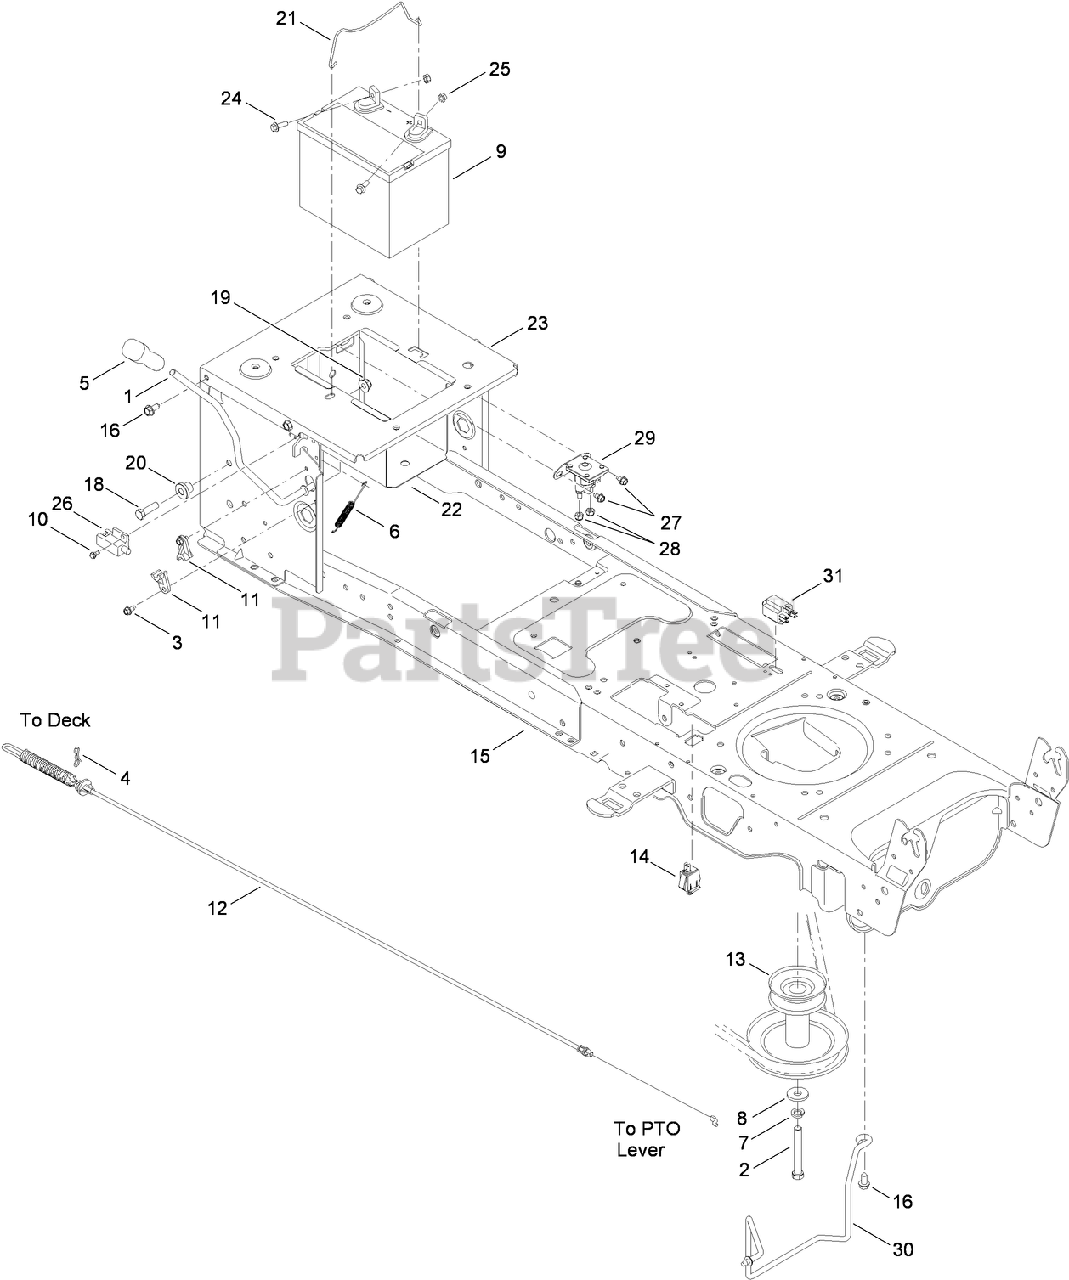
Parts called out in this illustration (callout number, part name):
1	PTO HANDLE ASM
3	SCREW-HWHTF
4	PIN-COTTER
5	GRIP-HANDLE
6	SPRING-EXTENSION
7	WASHER-LOCK
8	WASHER-FLAT
9	BATTERY-245, CCA,DRY (FLAT TOP)
10	BOLT-SHOULDER
11	BEARING-PTO
12	CABLE-ENGAGEMENT, DECK
13	PULLEY-ENGINE
14	SWITCH-PLUNGER, SNAP MOUNT
15	LOWER FRAME ASM
16	SCREW-TAP
18	SCREW-HH
19	NUT-LOCK, FLANGE
20	SPACER-SHOULDER
21	ROD-HOLDDOWN, BATTERY
22	TRAY-BATTERY
23	BRACKET-FRAME, SEAT
25	NUT-SEMS
26	SWITCH-INTERLOCK, NO/NC
27	SCREW-TAP
28	NUT-LOCK, FLANGE
29	SOLENOID-12V, 2 POST 2 TAB
30	ROD-KEEPER
31	SWITCH-3 POLE
